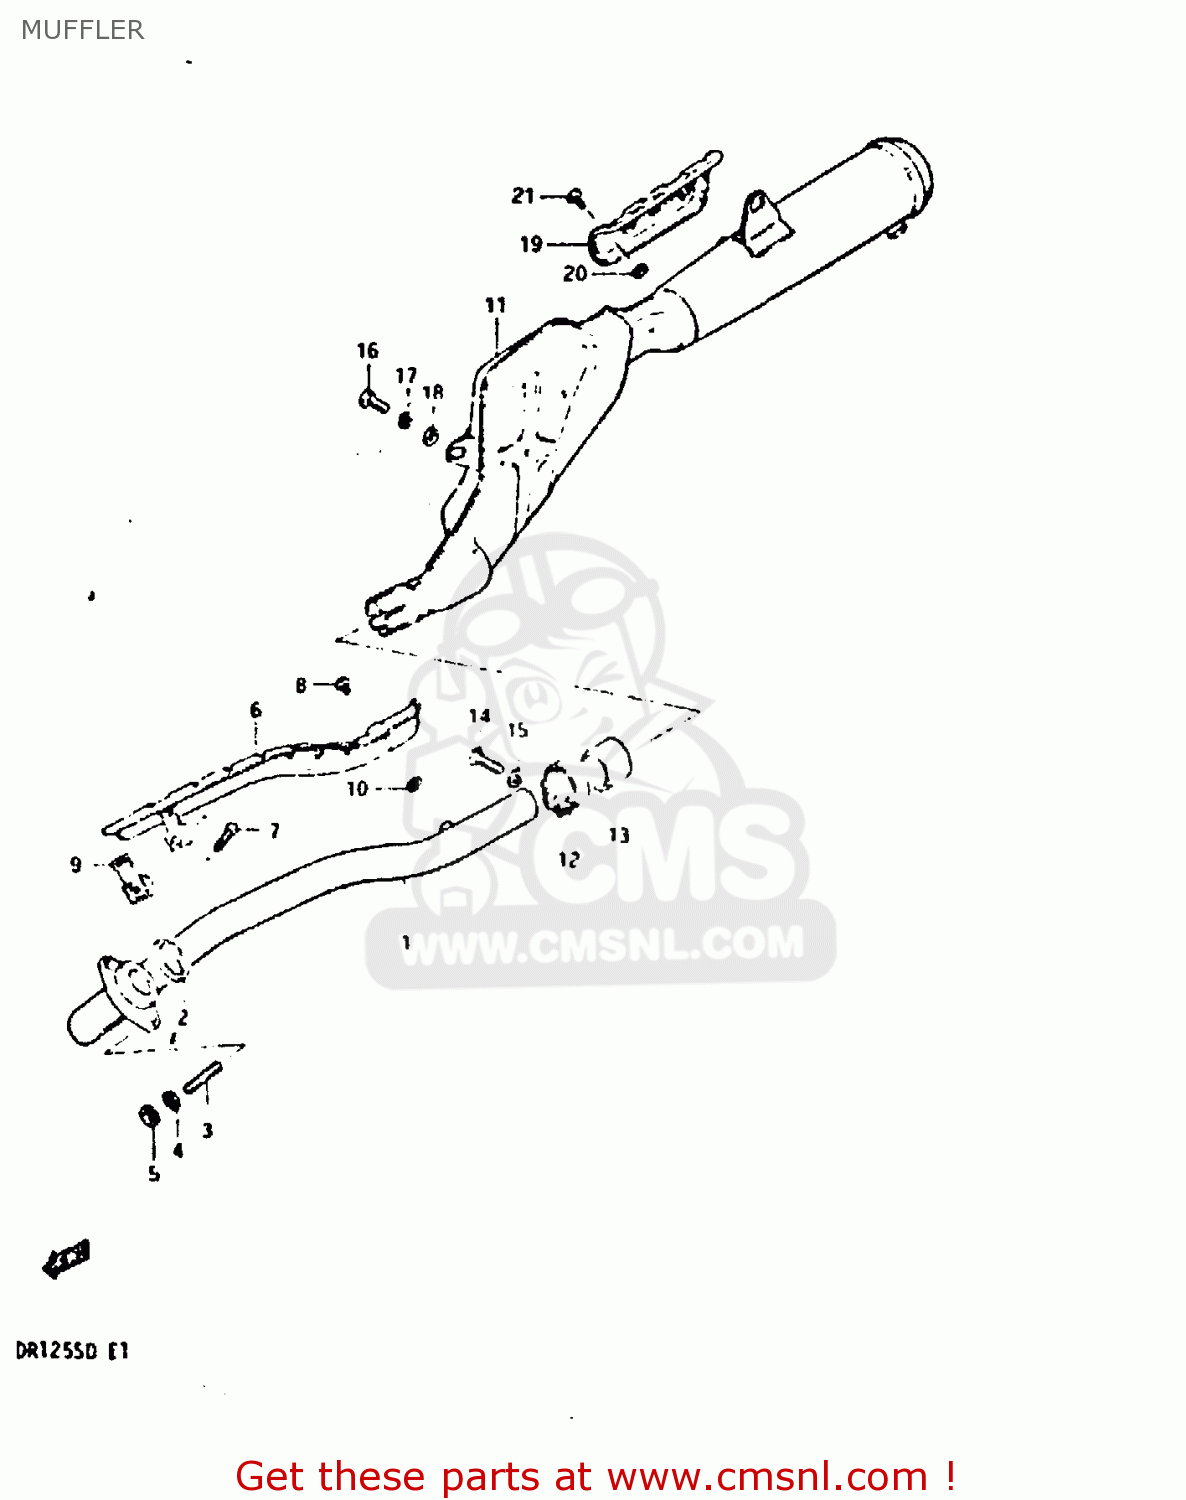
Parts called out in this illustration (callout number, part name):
1	PIPE,EXHAUST
2	GASKET,EXHAUST PIPE (NAS)
3	STUD BOLT L:20
4	LOCK WASHER
5	NUT
6	COVER,EXHAUST PIPE
7	SCREW 5X20
8	SCREW
9	CLAMP,EXHAUST PIPE COVER
10	GASKET 6.2X12X1.5 (MCA)
11	MUFFLER ASSY
12	CLAMP,MUFFLER CONNECTOR
13	CONNECTOR,MUFFLER
14	BOLT 8X35
15	WASHER,8.5X16X
16	BOLT
17	LOCK WASHER
18	WASHER,8.5X16X
19	COVER,MUFFLER
20	GASKET 6.2X12X1.5 (MCA)
21	SCREW
